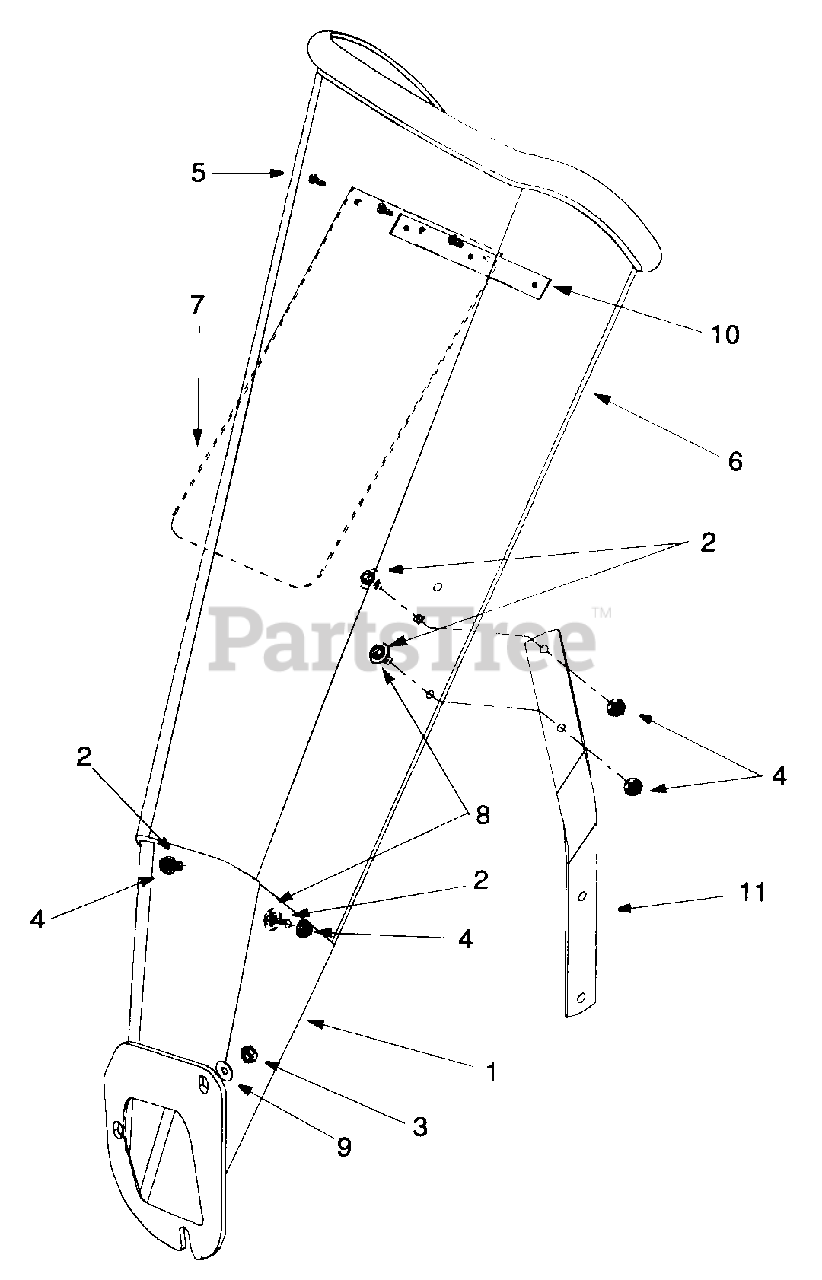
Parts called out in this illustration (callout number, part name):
3	Hex Nut, 5/16-18
4	Hex Flange Nut, 1/4-20
5	Pop Rivet
6	Chipper Chute, Black
7	Chute Flap
8	Flat Washer, .28 x .74 x .063
9	Bell Washer, .34 x .872
10	Chute Flap Strip
